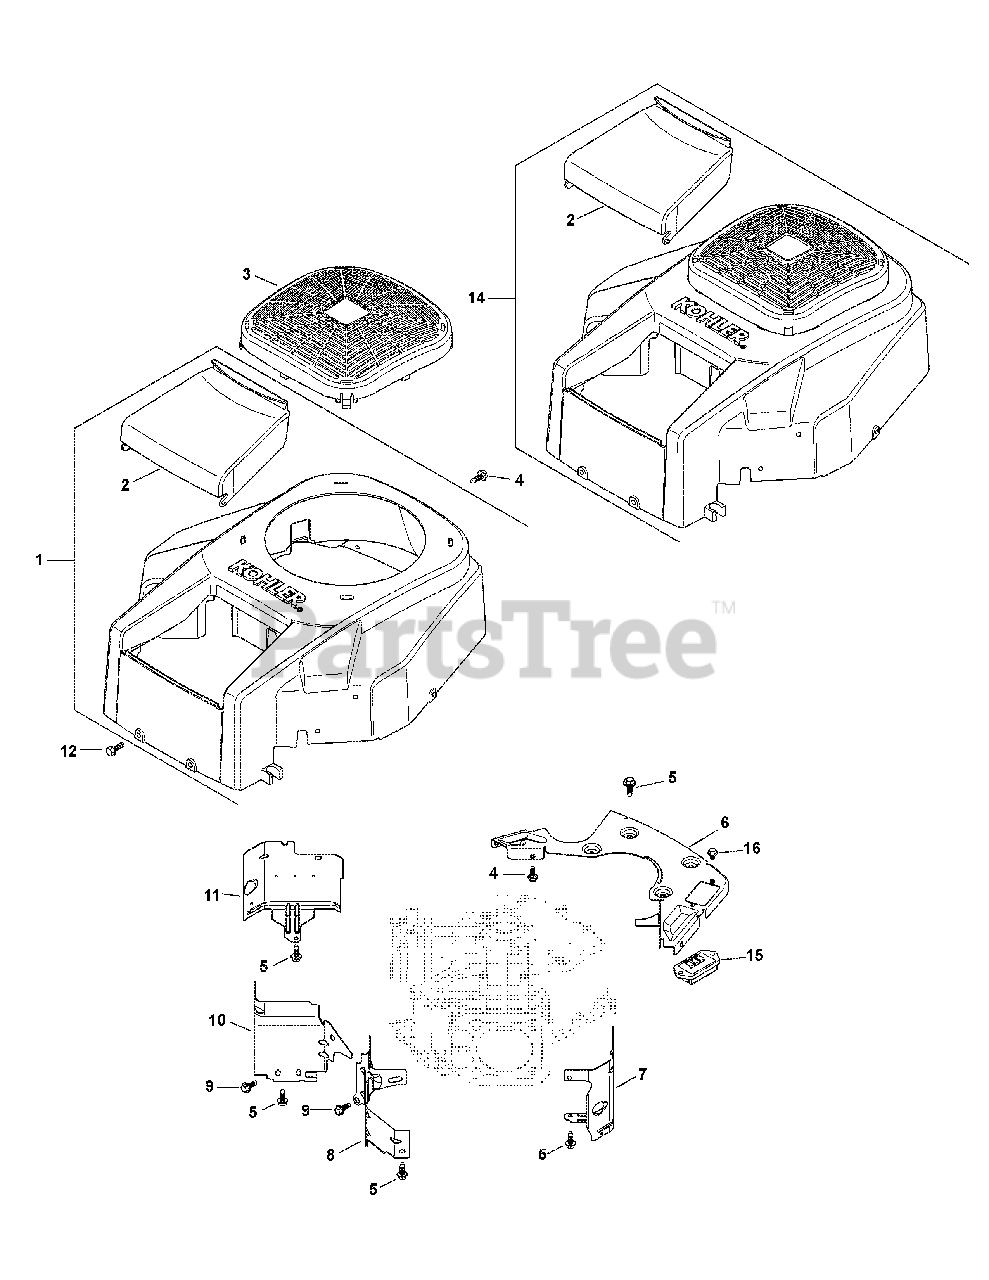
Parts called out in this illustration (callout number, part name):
1	Housing Blower Kit
2	Air Cleaner Cover
3	Fuse Block
4	Flg. Thd. Frm. Screw, M5 X 0.8 X 16
5	Flg. Thd. Frm. Screw, M6 X 1.0 X 16
6	Backing Plate Kit
7	Cyl. Barrel Baffle - #2 Side
8	Valley Baffle - #2 Side
9	Flg. Thd. Frm. Screw, M5 X .8 X 10
10	Valley Baffle - #1 Side
11	Cyl. Barrel Baffle - #1 Side
12	Tap Screw, M6 X 1.7 X 18
15	Regulator/Rectifier
16	Flg. Thd. Frm. Screw, M6 X 1.0 X 10
